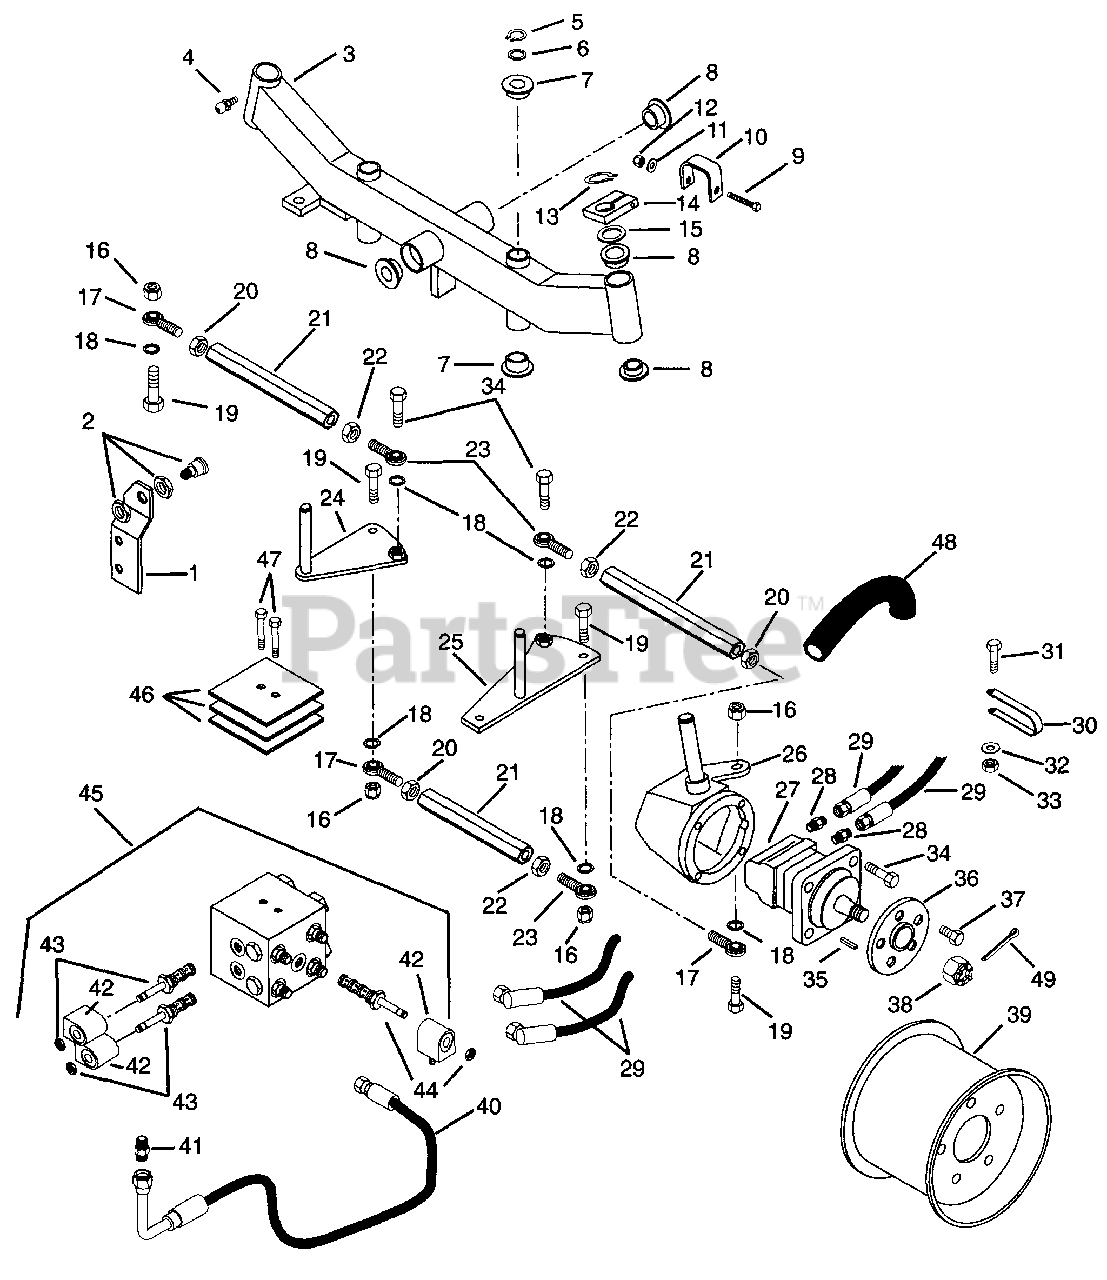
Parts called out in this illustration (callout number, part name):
2	Safety Switch
3	Axle Weldment
4	Fitting Lube .25-28 x .256
5	Ring-Retaining-External .689 x .077
6	Bearing-Needle-Thrust .752 x 1.24 x .031
7	Bushing-Flange .762 x 1.0 x .580 x 1.48
8	Bushing-Flange 1.020 x 1.385 x .75 x 1.75
9	Bolt-Hex .25-20 x 2.75 Grade 5
10	Bracket, Hose Loop
11	Washer-Flat-Steel .281 X .62 X .065
12	Nut-Locking .25-20
13	Ring-Retaining-External .906 x .078
14	Bracket Support
15	Washer-Hardened Thrust 1.002 x 1.552 x .030
16	Nut-Locking-Center .50-13 Grade 5
17	Assembly, Rod End Right Hand
18	Spacer .520 x .625 x .125
19	Bolt-Hex .50-13 x 2.00 Grade 5
20	Nut-Jam .50-20 Grade 2
21	Rod, Tie
22	Nut-Jam .50-20 Left Hand Grade 2
23	Assembly, Rod End Left Hand
24	Weldment, Steering Idler
25	Weldment, Steering Arm
26	Spindle Weldment Left Hand
26	Spindle Weldment Right Hand
27	Eaton 2000 Wheel Motor
28	Adapter, Hydraulic
29	Assembly, Hydraulic Hose
30	Clamp, Nylon
31	Bolt-Hex .38-16 x 1.00 Grade 5
32	Washer-Flat-Steel .406 x .812 x .065
33	Nut-Locking-Center .38-16
34	Bolt-Hex .50-13 x 1.50 Grade 5
35	Key-Square .313 x 1
37	Screw-Hex-Tapping .500-20 x .62
38	Nut-Hex Slotted 1-20
40	Assembly, Hydraulic Hose
41	Adapter, Hydraulic
42	Coil, Solenoid
43	Valve, 3-Way 12VDC Directional
44	Valve, 4-Way 12VDC Directional
45	Hydraulic Manifold Assembly
47	Bolt-Hex .31-18 x 1.25 Grade 5
48	Sleeve 18"
49	Pin-Cotter .12 x 2.0
